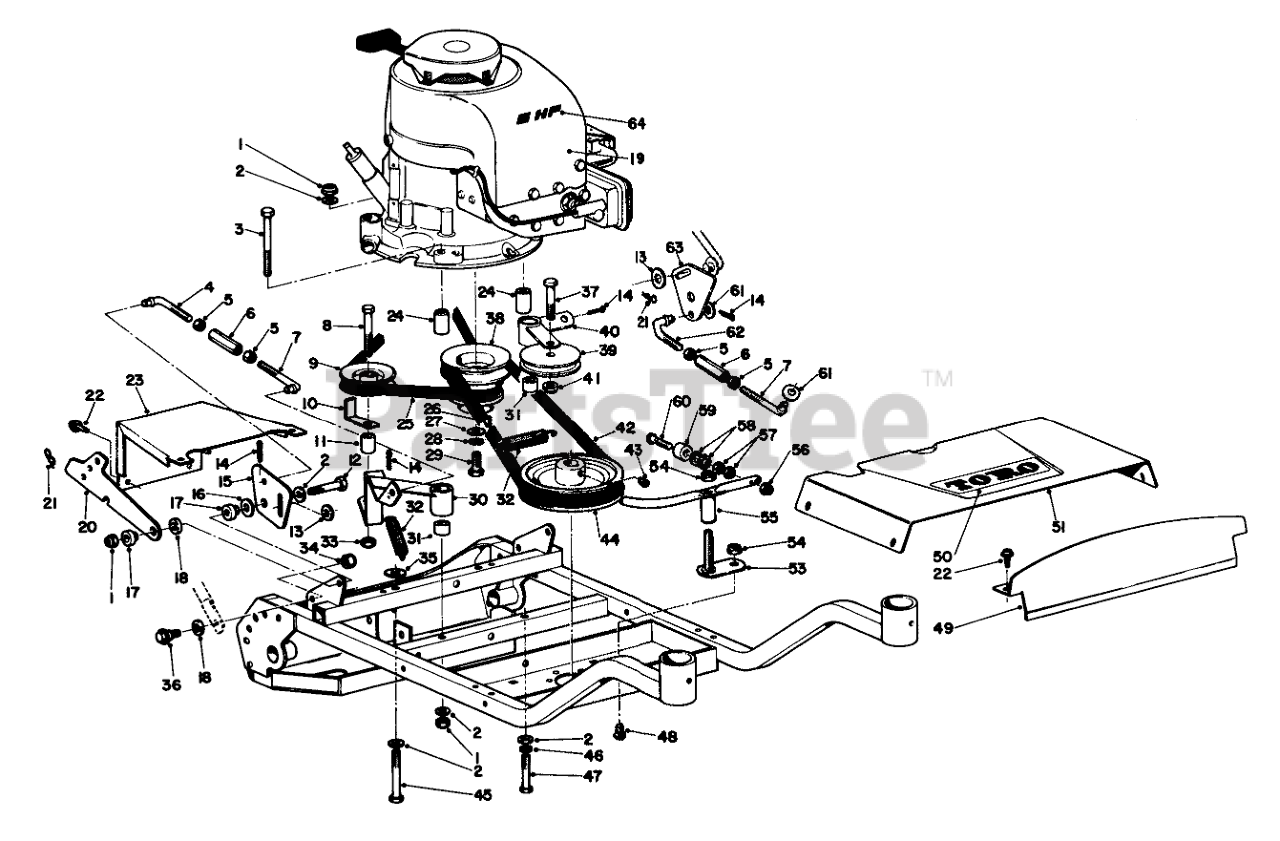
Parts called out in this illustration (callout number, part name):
1	Nut
2	WASHER-PLAIN
3	SCREW-HH
4	TRACTION LINK
5	NUT-HEX
6	CONTROL ROD SLEEVE
8	SCREW-HH
9	IDLER PULLEY R
11	Spacer
12	5/16-18 X 1-3/4 SCREW
13	Spacer
14	PIN-COTTER
15	Bell Crank
16	WASHER
17	PIVOT
18	SPACER
19	Engine
20	Latch
21	PIN-COTTER
22	10-16 X 3/8 THDG SCREW
23	Rear Shroud
24	ENGINE PIVOT SPACER
25	V-BELT
26	KEY-WOODRUFF
27	WASHER-FLAT
28	WASHER-LOCK
29	SCREW-HH
30	Arm & Bushing (Incl. Ref.#31)
31	BUSHING
32	EXTENSION SPRING
33	NUT-HEX
34	Nut
35	WASHER
36	SCREW-SHOULDER
37	Screw
38	Pulley
39	PULLEY B
40	Arm & Bushing (Incl. Ref. # 31)
41	Nut
42	CUTTER BELT
43	SCREW-HSH
44	CUTTER PULLEY
45	SCREW-HH
46	WASHER-LOCK
47	SCREW-HH
48	SCREW-CARR
49	Shroud Panel
50	Decal
51	FRONT SHROUD R
53	Base Pivot
54	NUT-HEX
55	Brake Arm
56	NUT-LOCK, NI
57	NUT-HEX
58	WASHER-FLAT
59	BUMPER
60	10-24X1-1/2 RND HD MS
61	WASHER
62	CUTTER LINK
63	CUTTR BELLCRANK WA R
64	Decal
